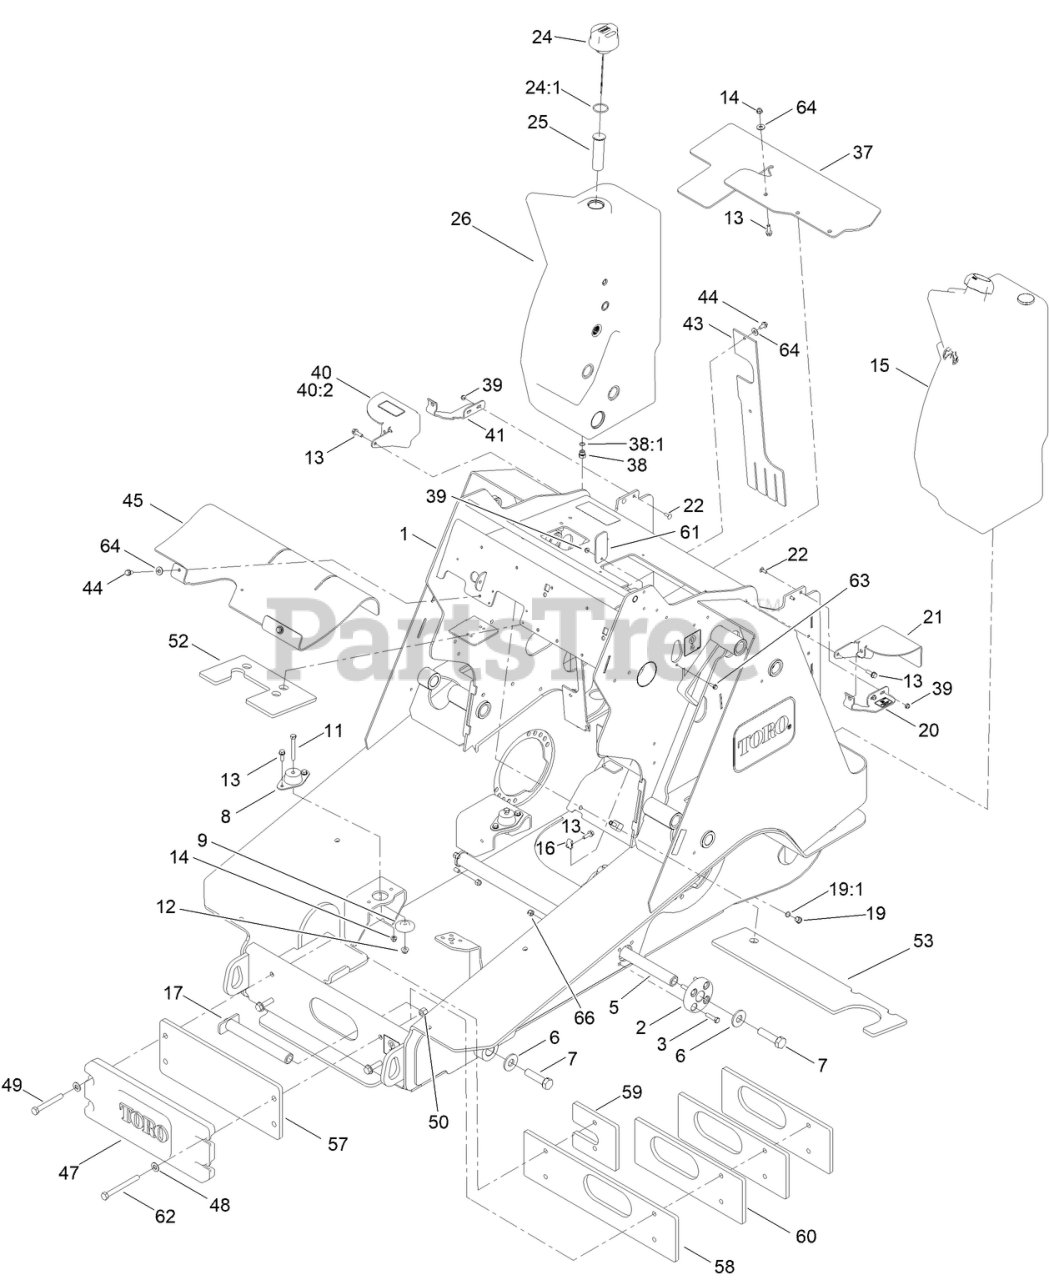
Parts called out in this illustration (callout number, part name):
1	MAIN FRAME ASM,
2	HUB-SHAFT
3	SCREW-HH
5	SHAFT-TRACK
6	WASHER
7	SCREW-HH
8	MOUNT-ENGINE
9	SUPPORT-ISOLATOR
11	SCREW-HH
12	NUT-HF, NI
13	SCREW-HHF
14	NUT-HF, NI
15	TANK ASM
16	NUT-CLIP, U
17	SHAFT-FRONT,TRACK
19	PLUG-HEX, HOLLOW
19:1	O-RING
20	BRACKET-TANK,(SERVICE)
21	BRACKET-TANK
22	BOLT-CARR
24	CAP-HYDRAULIC, VENTED BREATHER
24:1	O-RING
25	FILTER-SCREEN
26	HYDRAULIC TANK W/INSERTS
37	BAFFLE-RUBBER
38	PLUG-HH
38:1	O-RING
39	NUT-HF
40	BRACKET-HYD TANK
40:2	DECAL-HYD FLUID
41	BRACKET-TANK, RH
43	BAFFLE-SIDE
44	SCREW-HWHTF
45	BAFFLE-CONSOLE
47	COUNTERWEIGHT-FRONT
48	WASHER-FLAT
49	SCREW-HH
50	NUT-LOCK, NI
52	FOAM-HEAT SHIELD
53	FOAM-HEAT SHIELD
57	PLATE-WEIGHT
58	PLATE-WEIGHT
59	PLATE-WEIGHT
60	PLATE-WEIGHT
61	COVER-RUBBER
62	SCREW-HH
63	SCREW-HHF
64	WASHER-FLAT
66	NUT-LOCK
